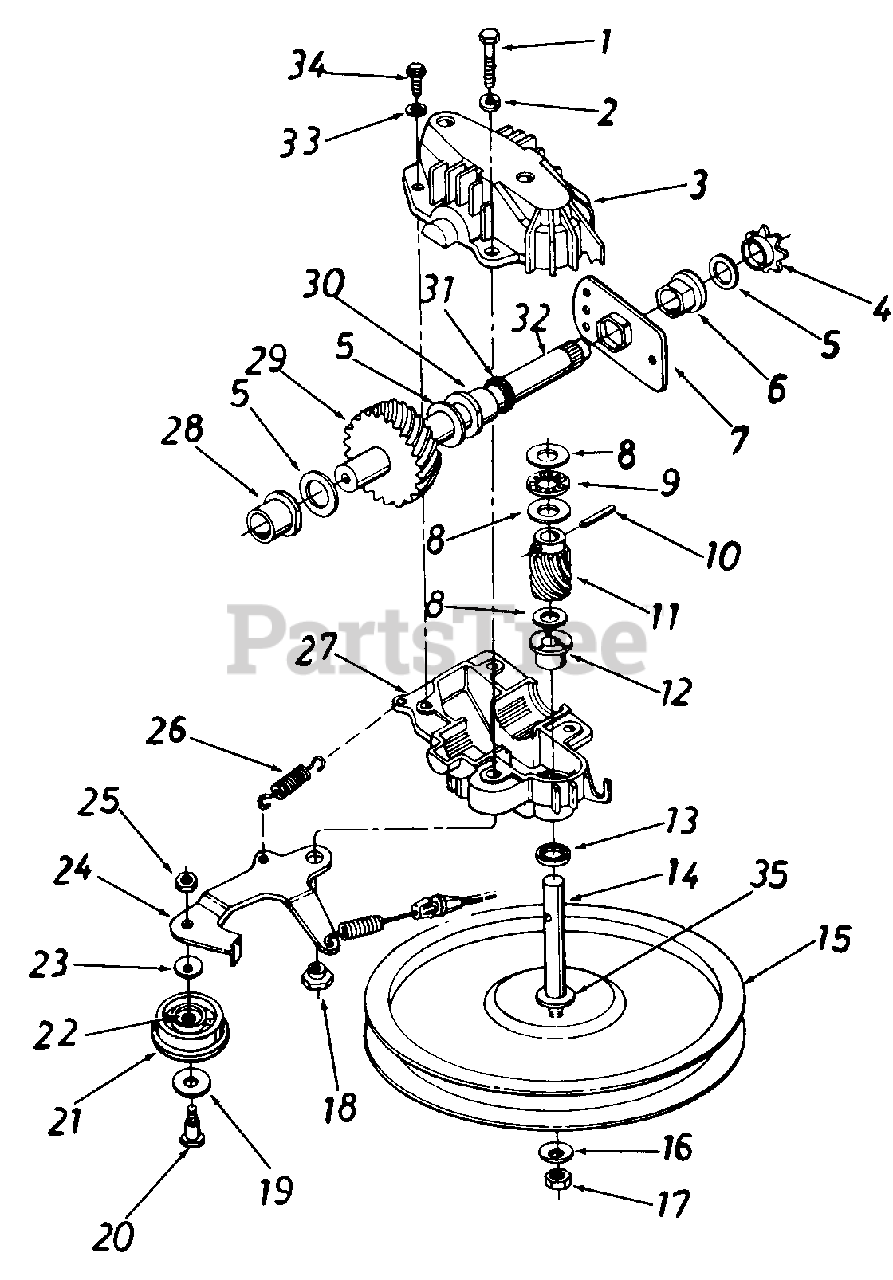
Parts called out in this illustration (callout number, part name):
1	Hex Bolt 1/4-20 x 1.25" Lg.
2	L-Wash. 1/4" I.D.
3	Upper Transmission Hsg. Half
4	#48 Sprocket 7 Tooth x 1/2 Pitch
5	Fl-Wash. 5/8" I.D. x .030
6	Hex Flange Brg. .631" I.D.
7	Hex Bearing Cup
8	Thrust Wash. .382" I.D. x .70" O.D.
9	Thrust Bearing .375" I.D. x .812" O.D.
10	Spring Pin Spir. 1/8" x .62" Heavy
11	11 Tooth Helical Gear
12	Flange Bearing
13	Oil Seal
14	Pulley-Transmission Shaft .375 O.D.
15	Fl-Pulley 5.06" O.D.
16	Bell-Wash. .265" I.D. x .75" O.D.
17	Hex Lock Nut 1/4-28 Thd.
18	Shld. Spacer .375" Dia. x .170
19	Fl-Wash. .390" I.D. x 1.0" O.D.
20	Shld. Bolt .375" Dia. x .40"
21	Fl-Idler Plastic 1.50" Dia. x .48
22	Needle Brg. .375" x .31
23	Bell-Wash. .265" I.D. x .75" O.D.
24	Idler Brk't. Ass'y.
25	Hex Patch L-Nut 1/4-28 Thd.
26	Extension Spring 1.12" Lg.
27	Lower Transmission Hsg. Half
28	Flange Bearing .566 Dia.
29	33 Tooth Helical Gear
30	Flange Bearing .629 Dia.
31	Oil Seal .625 Dia.
32	Gear Sprocket Shaft
33	L-Wash. #10
34	Hex B-Tap Scr. #10 x .62"
35	Hex Washer .26" x .88" x .04"
